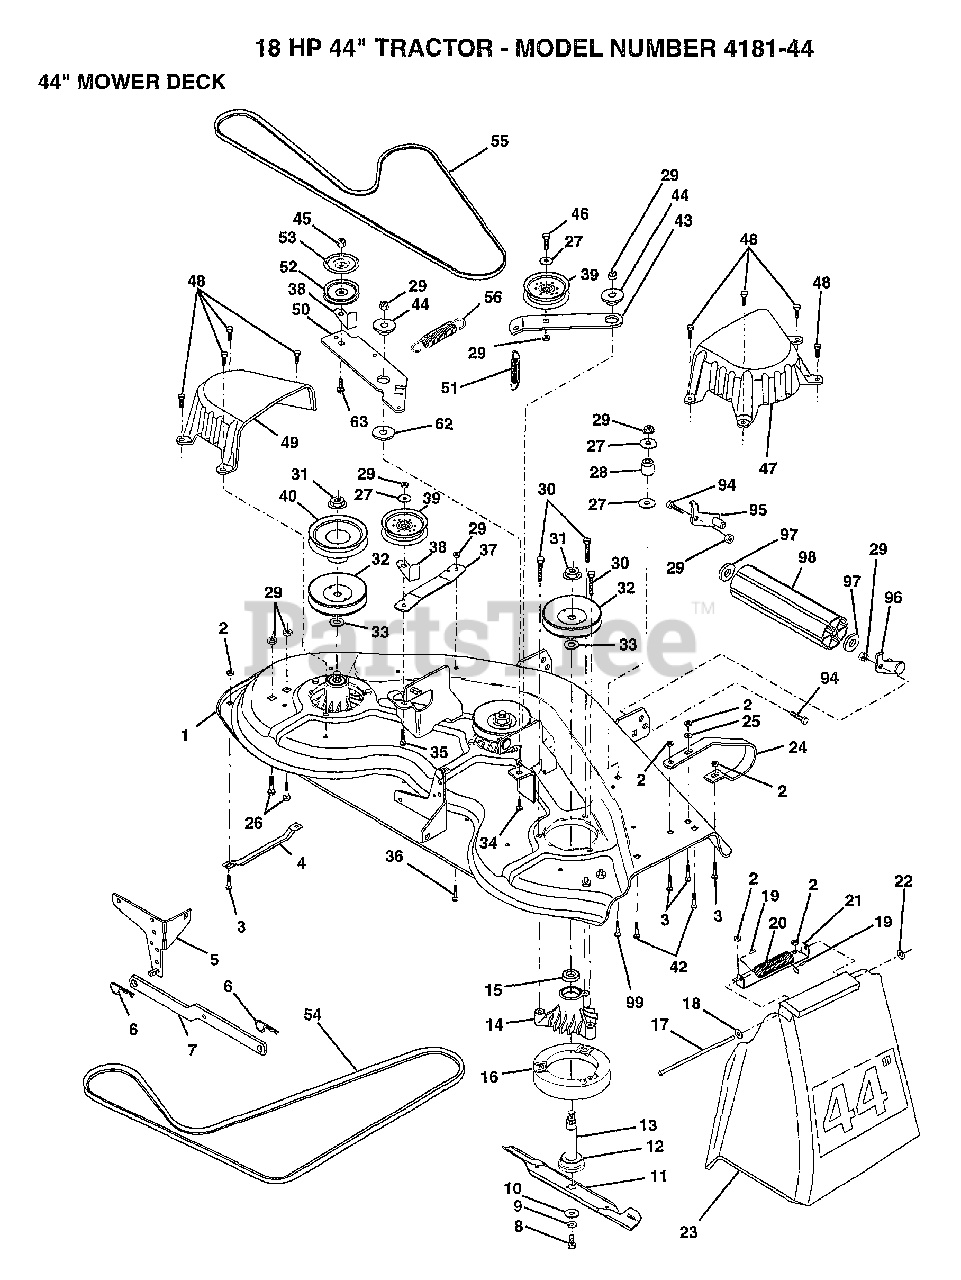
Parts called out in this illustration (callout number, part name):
1	"DECK ASM WELD44"""
2	NUT
4	RUNNER-LH M
5	BRKT.ASM.SW.44/50
8	BLADE BOLT
10	WASHER.HARD.BLADE
11	"BLADE.44"" HIPERF"
12	BEARING.BALL
13	SHAFT.ASM.W/BRNG
14	HOUSING.MAND.44.V
15	BEARING
16	STRIPPER RND MWR
17	ROD-HINGE T
18	WASHER
19	CAP-SLEEVE LT
20	SPRING TORSION
21	BRKT DEFLECTOR
22	NUT PUSH M
23	DEFLECTOR SHIELD
24	RUNNER.RH
25	WASHER M
26	BOLT
27	WASHER
29	NUT
33	WASHER
34	BOLT.3/8-14X1.25
35	BOLT
36	BOLT D
37	STIFFENER.ARM.IDL
39	FLAT IDLER PULLEY
40	"PULLEY.DRIVEN.44"""
42	BOLT
43	"ARM.IDLER.SEC.44"""
44	SPACER RETAINER
47	"COVER.MAND.RH.44"""
48	SCREW.1/4-20X5/8
49	COVER.MANDREL.LH
50	ARM.IDLER.PRIMARY
51	"SPRING.SEC.44""VEN"
52	PULLEY.IDLER.VGRO
53	SHIELD.IDLER.44.V
54	V-BELT.PRIM.78.5.
55	BELT-V.88.12.MW
56	SPRING.EXT.DECK.
62	HARDENED WASHER
63	BOLT.3/8-16X1.50
94	BOLT
97	WASHER
99	BOLT
